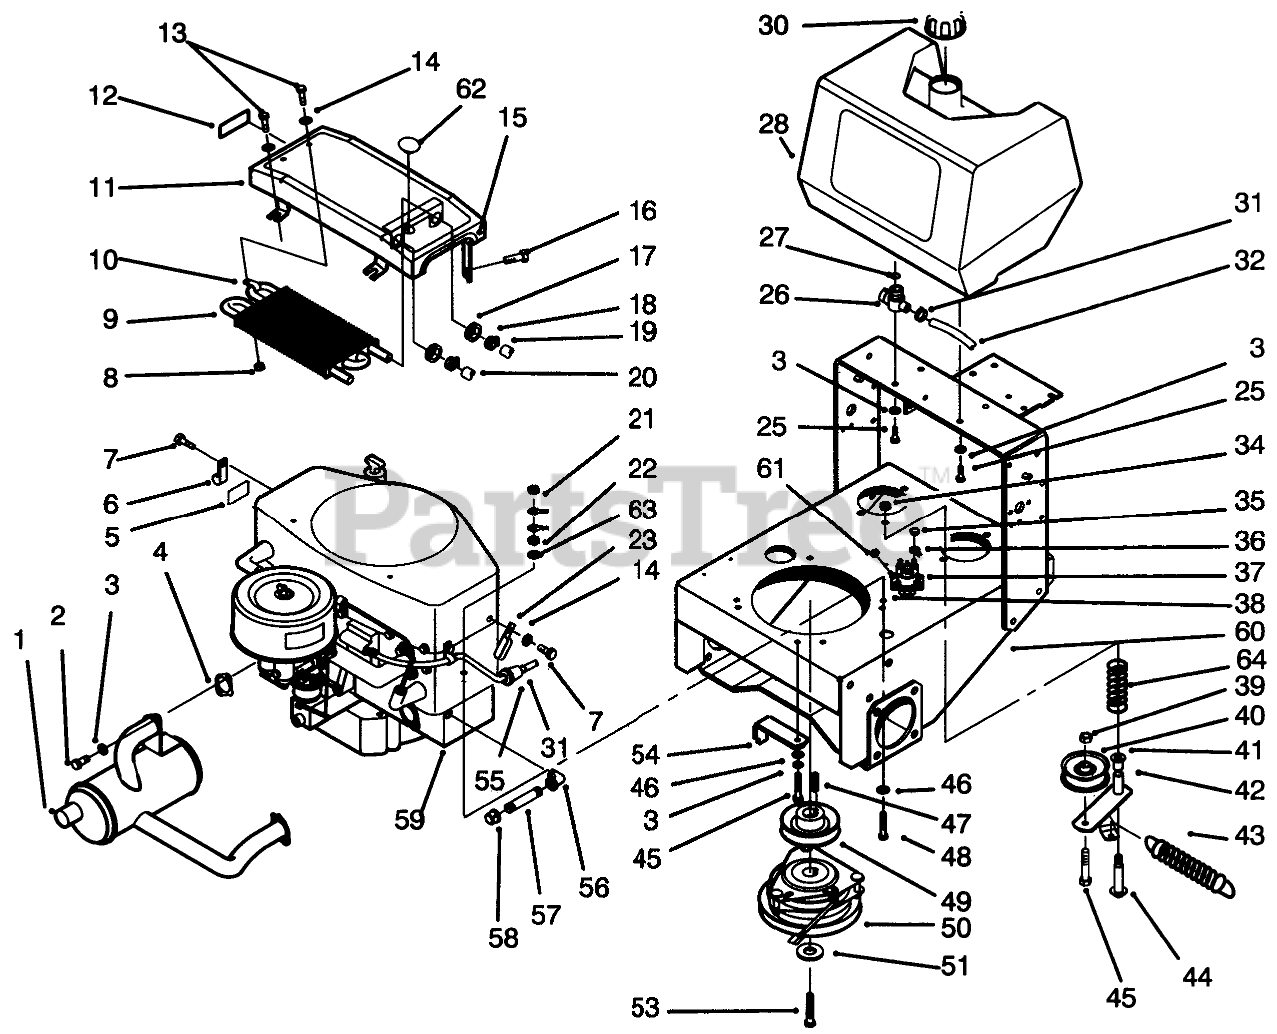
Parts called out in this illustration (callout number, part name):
1	MUFFLER
2	SCREW-HSH
3	WASHER-LOCK
4	EXHAUST GASKET F/W ENG.
5	DECAL-SURFACE, HOT
6	CLAMP
7	Screw-(Incl w/Engine)
8	NUT-LOCK, NI
9	Cooler-Oil
10	CLAMP-R
11	COOLER MOUNT WA 18 HPB
12	DECAL-FUEL SHUT OFF
13	SCREW-HH
14	WASHER-FLAT
15	TRIM-MOUNT, COOLER
16	Screw-(Incl. w/Engine)
17	GROMMET
18	CLAMP-HOSE
19	HYDRAULIC HOSE ASM
20	HYDRAULIC HOSE ASM
21	NUT-KEPS
22	NUT-HEX, SIDE DEFORM
23	CLAMP-R, DOUBLE
25	SCREW-HH
26	VALVE-FUEL
27	O-RING
28	FUEL TANK
30	GAS CAP ASM
31	CLAMP-HOSE
32	GAS HOSE
34	NUT-LOCK
35	NUT-KEPS
36	WIRE-SOLENOID/STARTER
37	SOLENOID
38	SCREW-HWH
39	NUT-LOCK, NI
40	PULLEY
41	BUSHING-FLANGE
42	Idler Assembly (Incl. Ref.#41)
43	SPRING
44	BOLT-WHEEL
45	SCREW-HH
46	WASHER-PLAIN
47	KEY-SQUARE
48	SCREW-HH
49	Pulley
50	CLUTCH/BRAKE
51	WASHER
53	SCREW-HH
54	Retainer-Clutch
55	Filter-Fuel (Incl w/Engine)
56	ELBOW-STREET, 90 DEG
57	NIPPLE
58	CAP-PIPE
59	Engine 18Hp. Kohler
60	Frame
61	NUT-KEPS
62	PLUG-PLASTIC
63	WASHER-LOCK
64	SPRING-COMPRESSION
